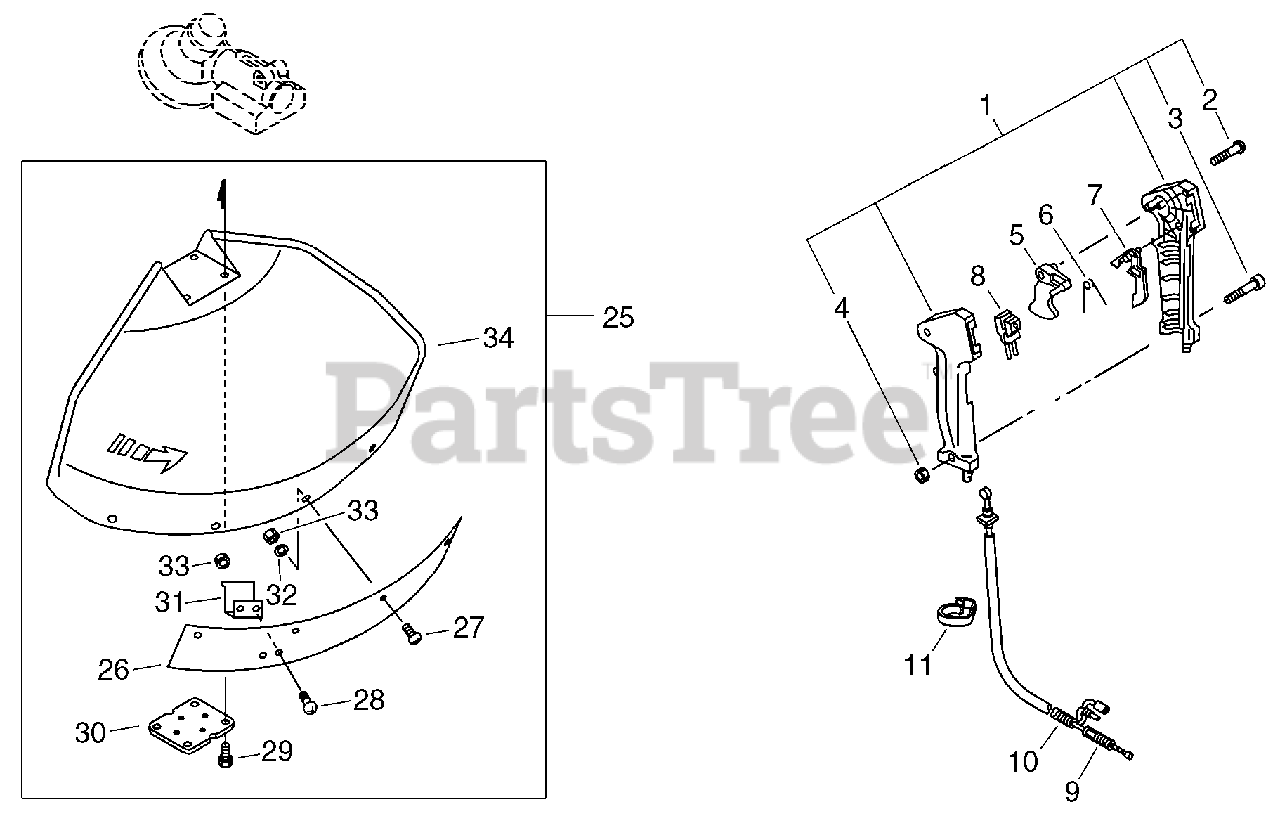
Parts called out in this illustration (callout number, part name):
1	CONTROL HANDLE KIT
2	SCREW 3×25
3	SCREW 5×30
4	NUT M5
5	TRIGGER, THROTTLE
6	SPRING, TORSION
7	LOCKOUT, THROTTLE
8	SWITCH, ON-OFF
9	CABLE, THROTTLE
10	TUBE, FLEXIBLE 7×790
25	DEBRIS SHIELD ASSY
26	EXTENSION, SHIELD
27	SCREW 5×18
28	BOLT 5×14
29	BOLT 5×25
30	PLATE, SHIELD
31	CUTTER, LINE
32	WASHER 5.5×12×0.8
33	NUT M5
34	SHIELD, DEBRIS
